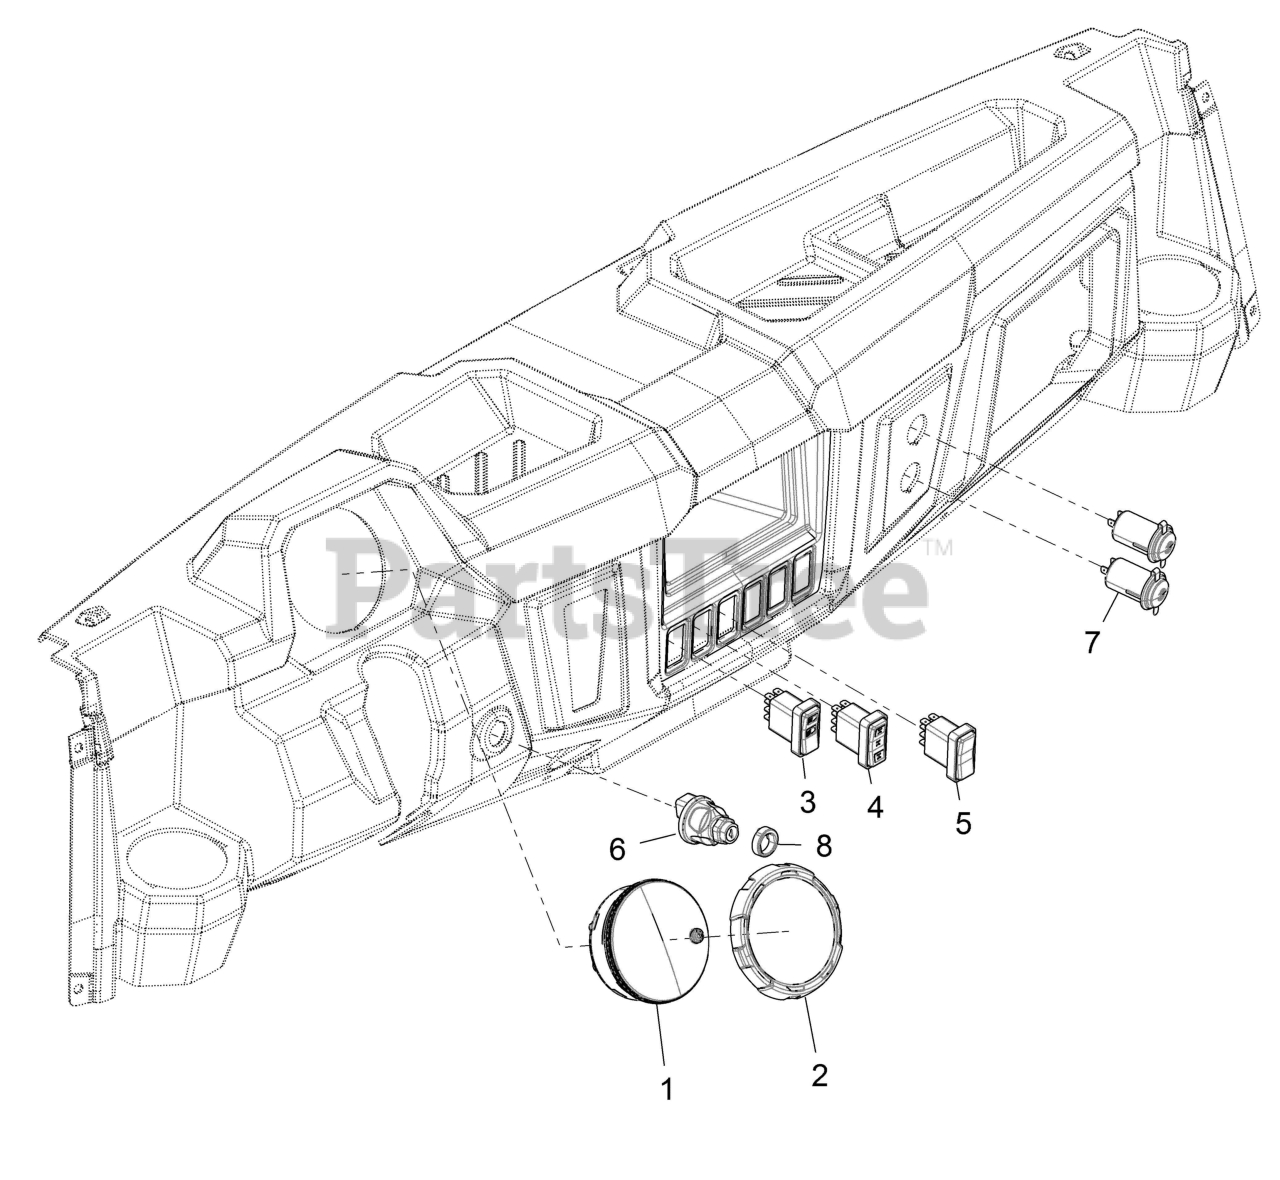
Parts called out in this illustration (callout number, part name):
1	ASM-CLUSTER,CPIA3,OSPS,MD
1	MOUNT-RUBBER,INSTR. CLUSTER
2	BEZEL-INSTRUMENT CLUSTER
3	SWITCH-HEADLIGHT
4	SWITCH-AWD
5	SWITCH-BOX LIFT,MOMENTARY
6	SWITCH,KEY,ARIENS
7	RECEPTACLE-POD MNT,12 VOLT
8	SPACER, KEY, SWITCH
